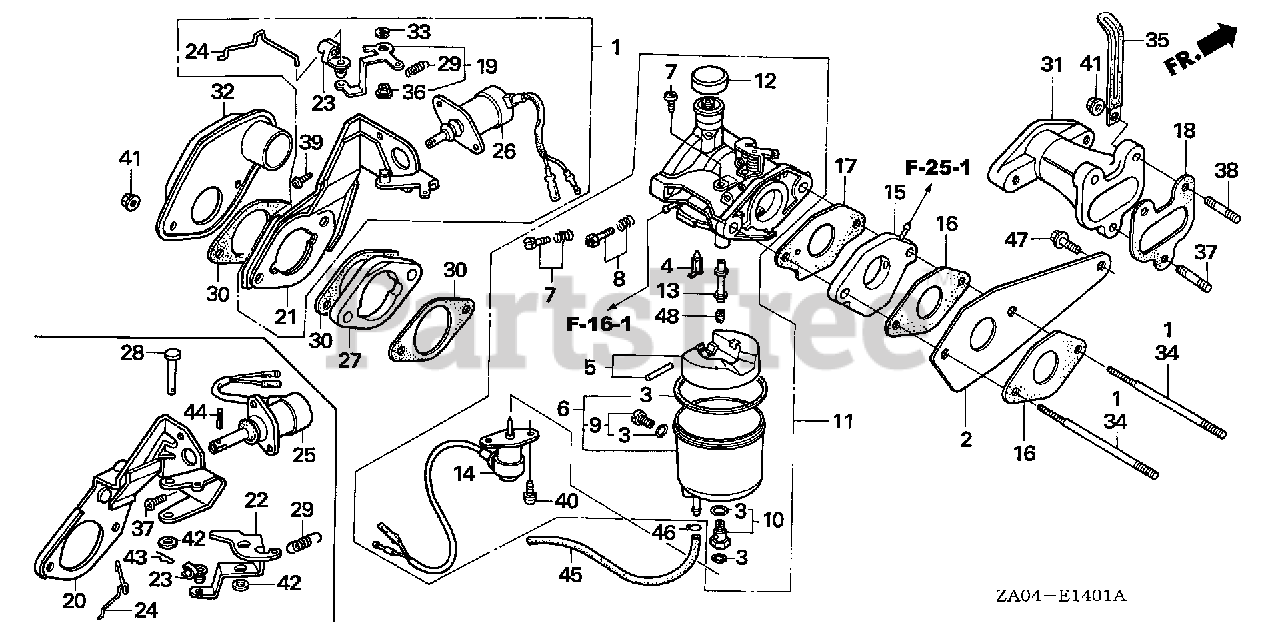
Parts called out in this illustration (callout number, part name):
1	STAY SET, SOLENOID (NOT AVAILABLE)
2	STAY, TIMING BELT
3	GASKET SET
4	VALVE SET, FLOAT
6	CHAMBER SET, FLOAT
7	SCREW SET A
8	SCREW SET A
9	SCREW SET, DRAIN
11	CARBURETOR ASSY. (BB50C A/B) (NOT AVAILABLE)
12	CAP, CHOKE DUST
13	NOZZLE, MAIN (NOT AVAILABLE)
14	VALVE ASSY., SOLENOID
15	INSULATOR, CARBURETOR (NOT AVAILABLE)
16	GASKET, INSULATOR
17	GASKET, CARBURETOR
18	GASKET, IN. MANIFOLD
19	LEVER, SOLENOID CHOKE (NOT AVAILABLE)
20	STAY, SOLENOID (NOT AVAILABLE)
21	STAY, SOLENOID
22	LEVER, CHOKE SOLENOID (NOT AVAILABLE)
23	JOINT, ROD
24	ROD, CHOKE (NOT AVAILABLE)
25	SOLENOID, CHOKE (N/A: USE ALTERNATE P/N 06162-ZA0-315)
26	SOLENOID, CHOKE (NA USE ALT:06162-ZA0-315)
27	SPACER (NOT AVAILABLE)
28	PIN, CHOKE SOLENOID
29	SPRING, CHOKE RETURN
30	GASKET, AIR CLEANER
31	MANIFOLD, IN. (NOT AVAILABLE)
32	PIPE, AIR IN. (NOT AVAILABLE)
33	E-RING (4MM)
34	BOLT, STUD (8X113)
35	CLIP, WIRE
36	BUSH, CHOKE LEVER
37	BOLT, STUD (6X32)
38	BOLT, STUD (6X35)
38	BOLT, STUD (6X28)
39	SCREW, PAN (5X8)
40	SCREW-WASHER (5X12)
41	NUT, FLANGE (6MM)
42	WASHER, PLAIN (5MM)
43	PIN, LOCK (5MM)
44	PIN, SPRING (2X8)
45	BULK HOSE, FUEL (3.5X3000) (3.5X320)
46	CLIP, TUBE (B7)
47	BOLT, FLANGE (6X12)
48	JET, MAIN (#90)
48	JET, MAIN (#92)
48	JET, MAIN (#95)
